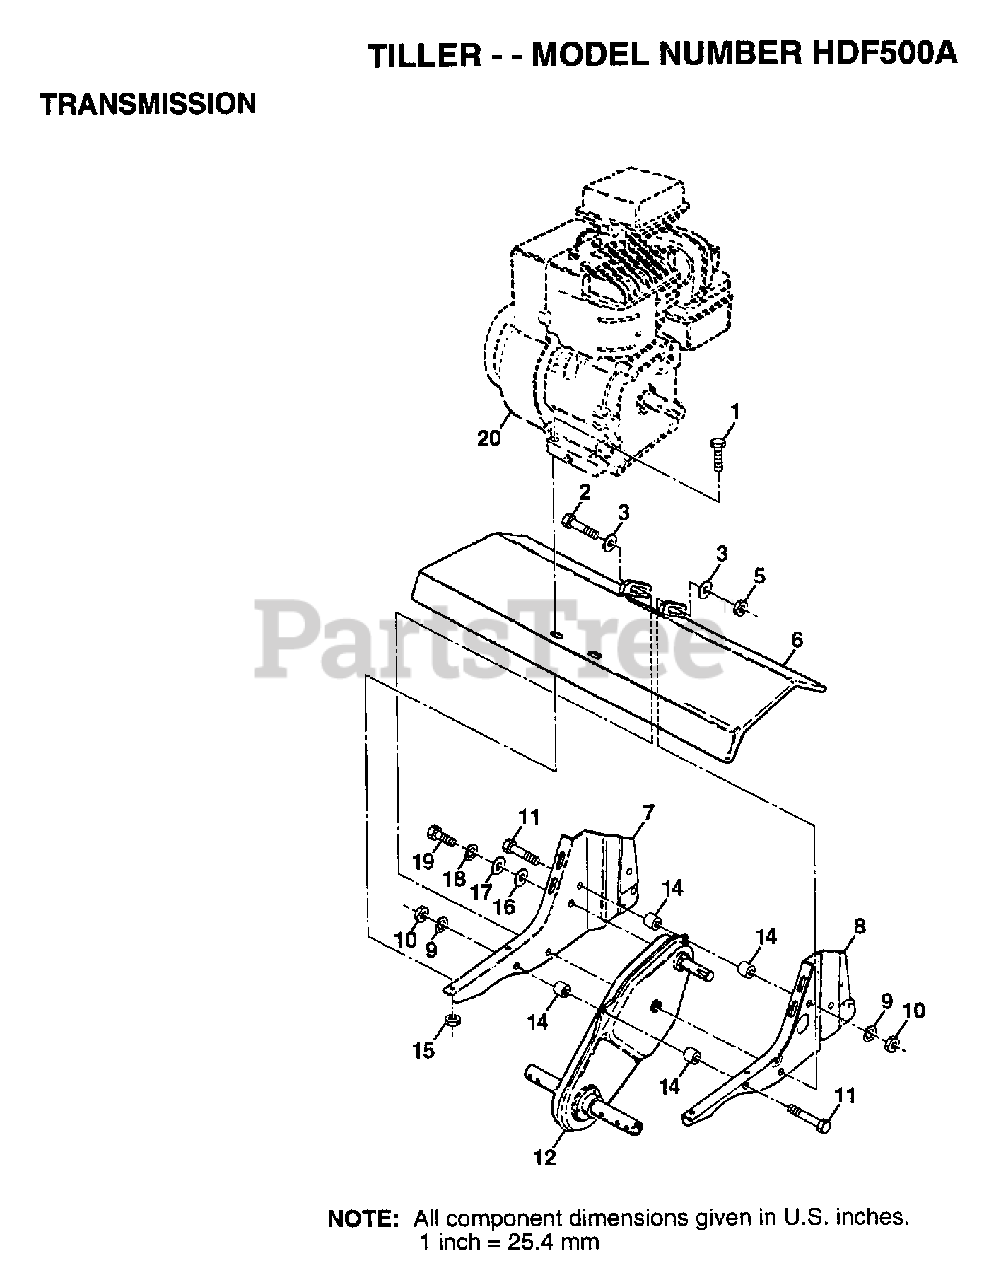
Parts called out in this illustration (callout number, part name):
1	BOLT.HEX.5/16-1.5
2	BOLT HEX 3/8-16
3	WASHER
5	NUT
6	SHIELD.PNT.TINE
8	BRACKET.ENG.LH.
9	LOCKWASHER
10	NUT.HEX.5/16-18
14	SPLIT SPACER RT
16	WASHER
17	WASHER
18	LOCKWASHER
19	BOLT
